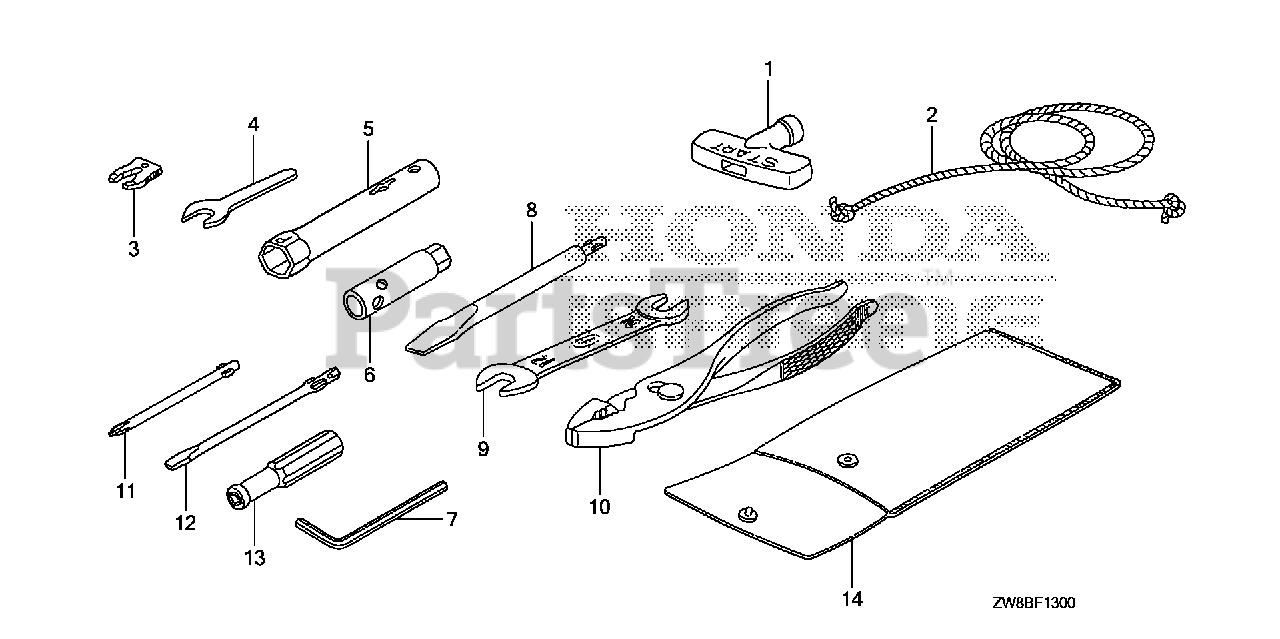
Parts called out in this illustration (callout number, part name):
1	GRIP, STARTER
1	KNOB, RECOIL SRARTER
2	ROPE, RECOIL STARTER (1300MM)
3	CLIP, EMERGENCY LOCK
4	SPANNER (8MM) (NOT AVAILABLE)
5	WRENCH, SPARK PLUG
6	WRENCH, BOX (10MM)
7	WRENCH, HEX. (4MM)
8	SCREWDRIVER, CHECK BOLT
9	SPANNER (10X12)
10	PLIERS (135) (KOWA)
10	PLIERS (135)
11	DRIVER 1, PLUS SCREW (NO.2)
12	DRIVER 3, MINUS SCREW (NO.2)
13	GRIP, SCREW DRIVER
14	BAG, TOOL (160MM)
